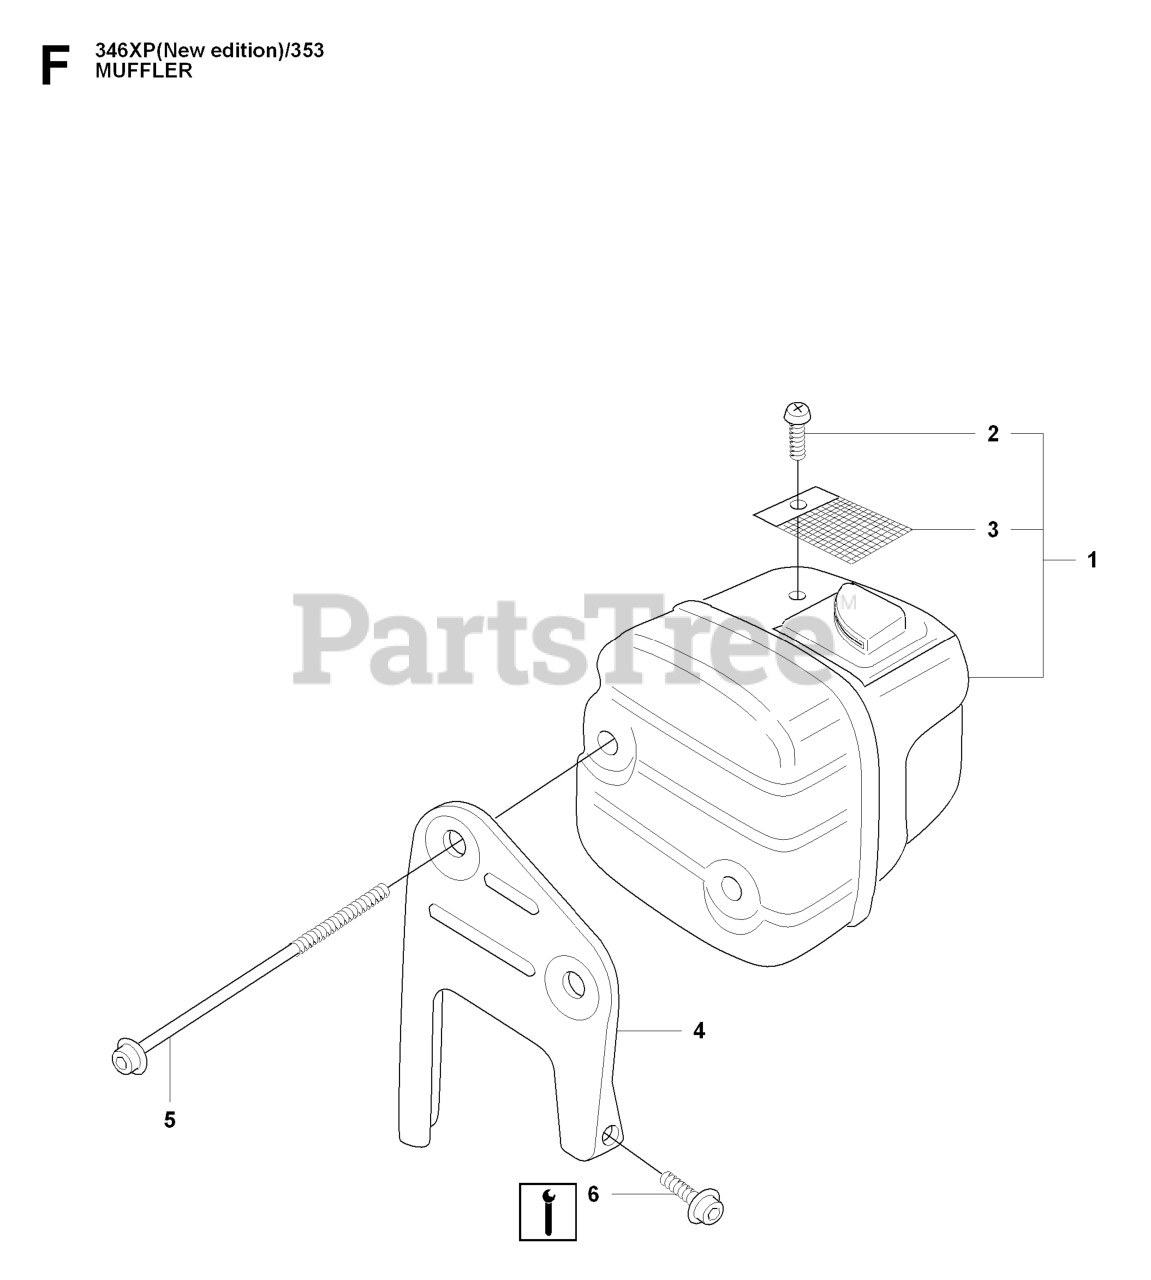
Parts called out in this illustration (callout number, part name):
1	MUFFLER
1	MUFFLER ASSY
2	SCREW
3	RP SCREEN
